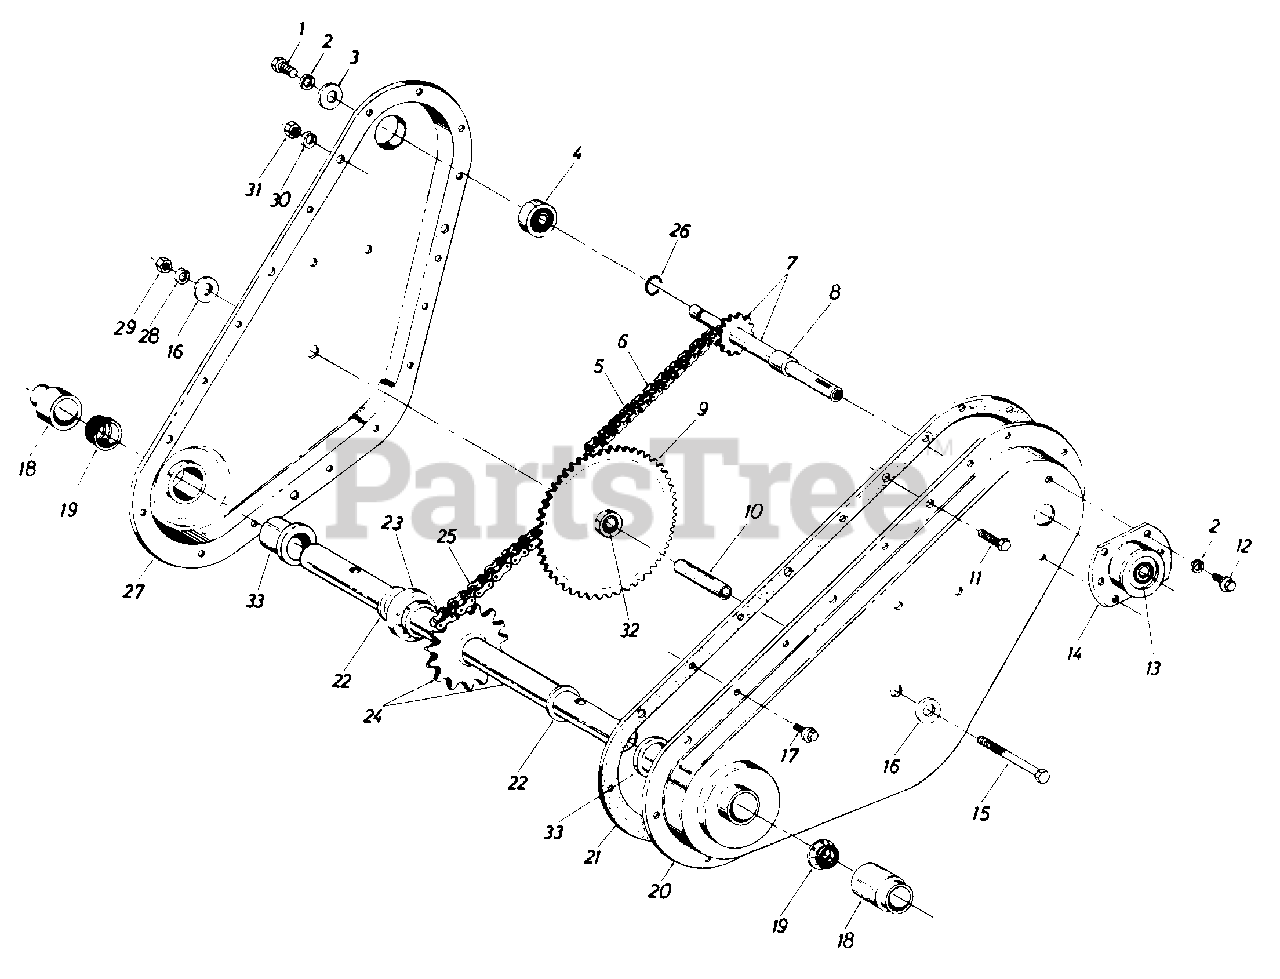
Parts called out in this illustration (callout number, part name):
1	Hex L-Bolt 1/4-28 X .625" Lg.
2	L-Wash. 1/4" I.D.
3	Fl-Wash. .25" I.D. x .93" O.D. x .125" Thk.
4	Bearing .62" I.D. x 1.38" O.D. x .437" Thk.
5	#35 Chain 3/8" Pitch x 52 Links Endless
6	Master Link
7	Input Shaft Assembly
8	Spacer
9	Sprocket Assembly
10	Sprocket Hub Tubing 3/8" I.D. x 5/8" O.D. x l.9" Lg.
11	Hex Bolt 5/16-18 x .625" Lg.
12	Hex Wash. Hd. Self-Tap Scr. 1/4-20 X .50" Lg.
13	Bearing .625" I.D. x 1.38" O.D. x .437" Thk.
14	Bearing Housing
15	Hex Bolt 3/8-24 x 2.75" Lg.
16	Fl-Wash. 3/8" I.D. x 1.25" O.D. x .100" Thk.
17	Hex Wash. Hd. Self-Tap Scr. 1/4-20 X .50" Lg.
18	Dust Cap
22	Thrust Wash. 1.00" I.D. x .030" Thk.
23	Step Spacer
24	Tine Shaft Assembly
25	#50 Chain 5/8" Pitch x 46 Links Endless
26	Snap Ring 5/8" Dia. Shaft
29	Hex Nut 3/8-24 Thd.
30	L-Wash. 5/16" I.D.
31	Hex Nut 5/16-18 Thd.
32	Bearing
33	Bearing
